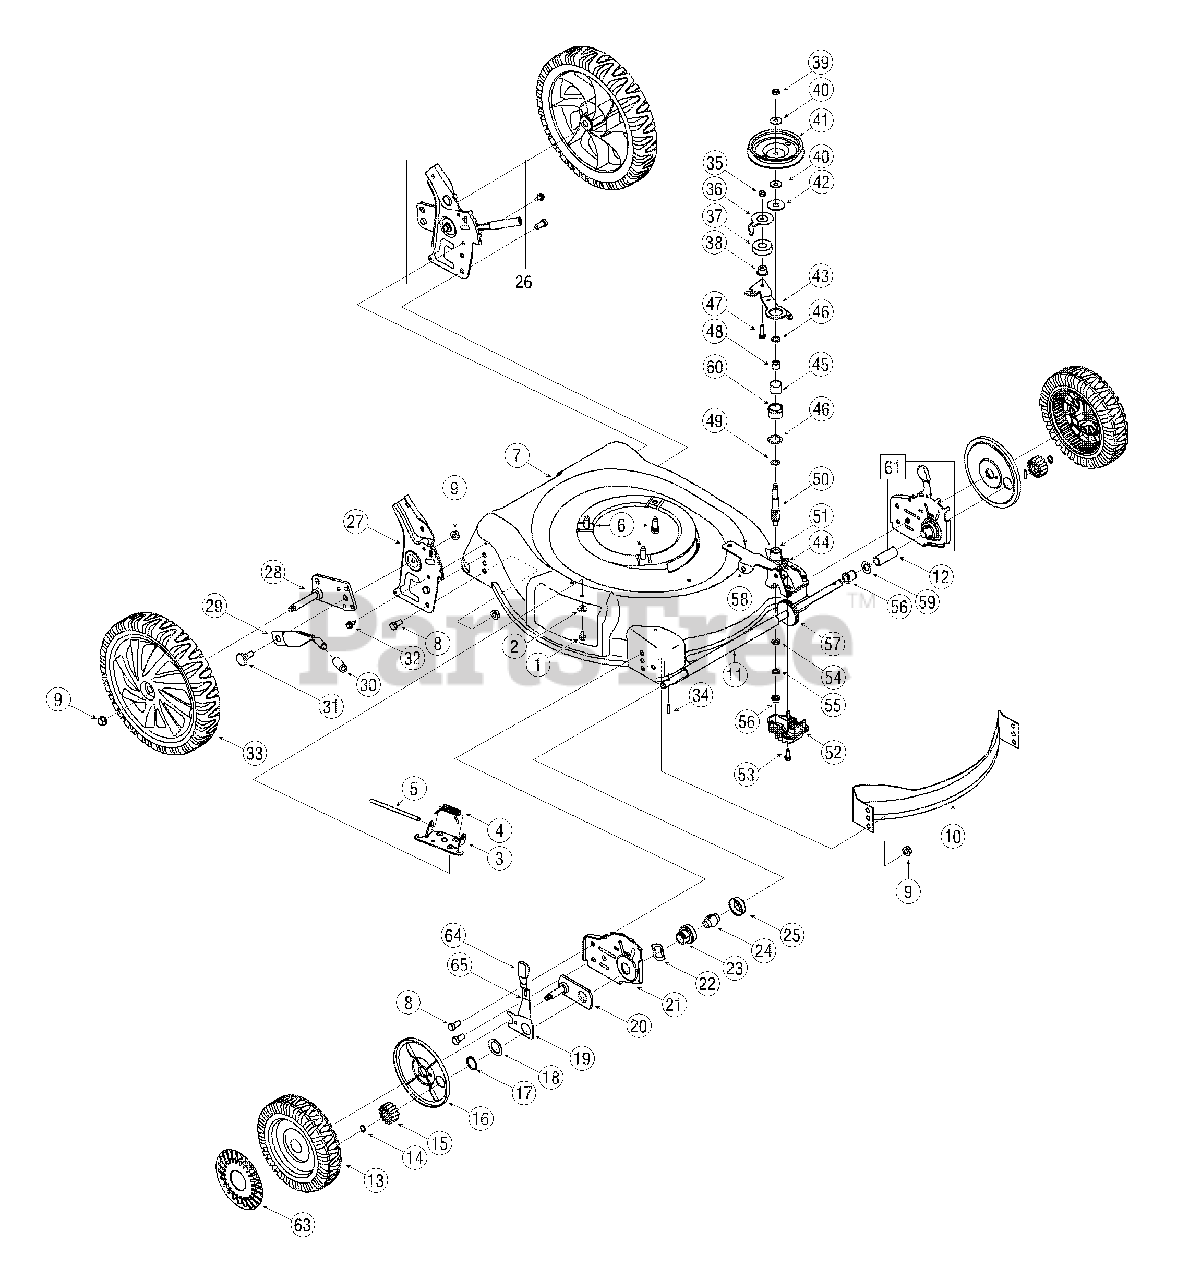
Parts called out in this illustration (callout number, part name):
1	TT Screw 1/4-20 x 0.5
2	Bell Washer.265 x 0.75
3	Deflector Chute Adapter
4	Torsion Spring
5	Hinge Pin
6	Self-Tapping Sems Screw
9	Hex Nut 3/8-16
10	Front Baffle
11	Sleeve Spacer 10.1" Lg.
12	Slev. Spacer 2.1" Lg.
13	Wheel 8 x 2.125 Black Zag Gear
15	Gear 14T RH FWD
16	Wheel Dust Cap
19	Lever Assembly RH
20	Pivot Plate Assembly
23	Bearing Support
24	Bearing Sleeve
25	Bearing Retainer
26	Handle Bracket Assembly - LH
27	Handle Bracket - RH
28	Pivot Bar RH
29	Height Adjustment Lever
31	Shoulder Scr.500 Dia. x.434
32	Tt Screw 1/4-20 x.625"
33	Wheel, 12 x 2.125 Zag Gray IDL
34	Dowel Pin
37	Ball Bearing
38	Flange Bearing
39	Hex Jam Nut 5/16-24
40	Bell Washer.325 x.930 x.45
41	Pulley, 3.82 x.313 x.68
42	Flat Washer.422 x 1.38 x.060
43	Front Idler Assembly
44	Extension Spring
45	Bearing Sleeve
46	Fl-Wash.865 x 1.145 x.030
47	Hex Screw 1/4-28 x 1.0
48	Needle Bearing.438 x.625 x.500
49	Flat Washer.504 x.700 x.030
50	Pinion Shaft
51	Upper Housing
52	Lower Housing
53	Hex Screw w/Washer 1/4-20 x.750
54	Thrust Washer.375 x.070 x.030
55	Thrust Washer.388 x.625 x.062
56	Flange Bearing
58	Idler Cable Bracket Assembly
59	Oil Seal
61	Height Adjustment Assembly LH
62	Transmission Assembly Comp.
63	Radial Spoke Hubcap
64	Adjustment Knob
65	Front Lever RH
